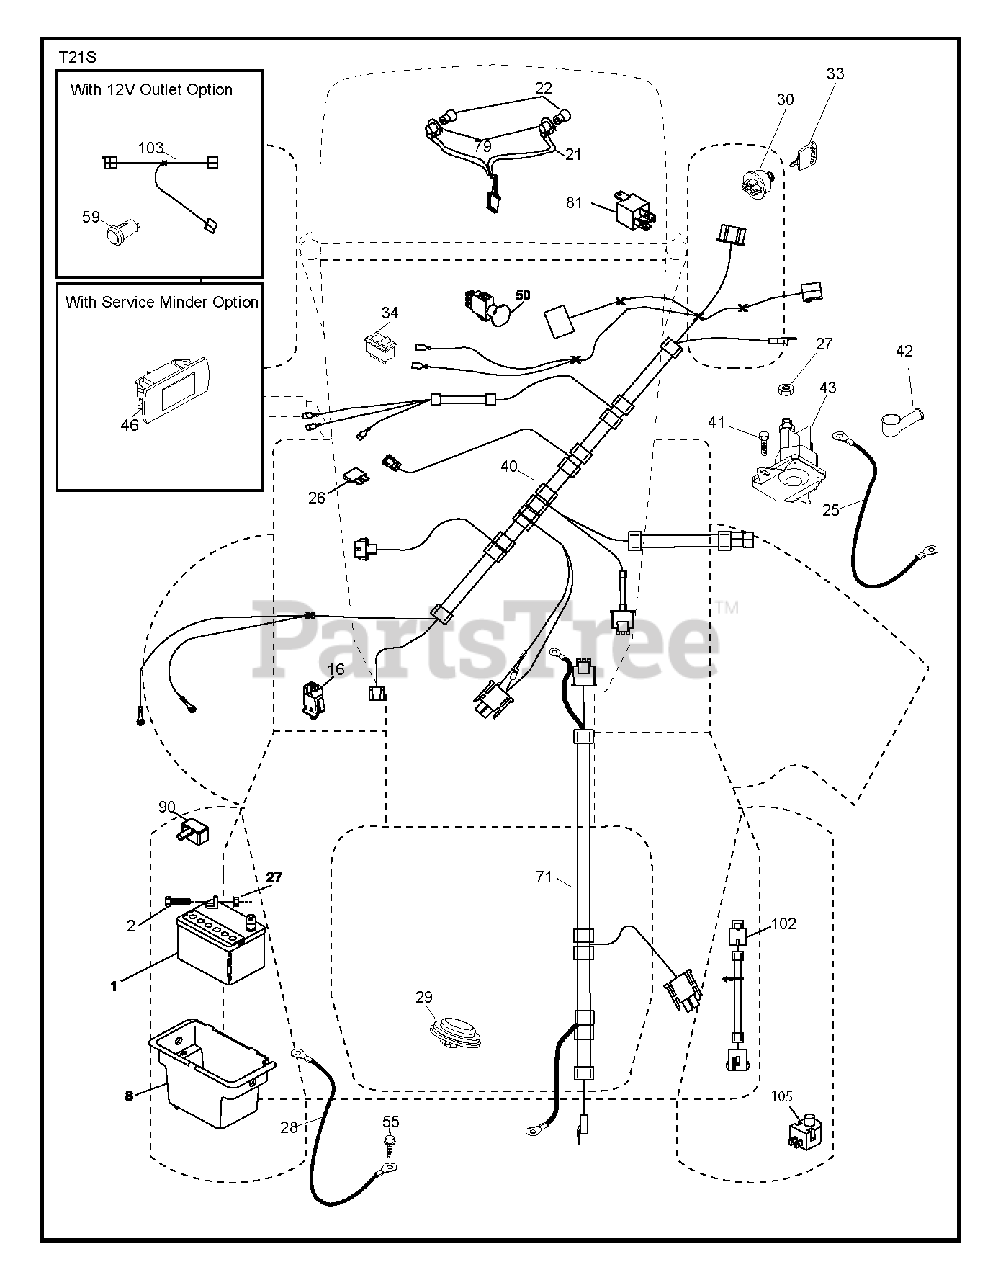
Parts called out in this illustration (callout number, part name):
1	Battery, Dry 30 Amp
2	BOLT.HEX.1/4.X.3/4.DICHROMATE
8	BOX.BATTERY.MNT.REAR.L
16	SWITCH INTERLOOK PUSH-IN
21	HARNESS.LIGHT W/4152J BULBS
25	CABLE.STARTER.8GA.17.5
26	FUSE 20AMP
27	NUT
28	CABLE.GROUND.REAR.BATTERY.8G
29	SWITCH.SEAT.DELTA.OPC.
30	SWITCH.IGN.DELTA.W.LGH.ROS
33	KEY.CHAIN.BLISTER.PACK.GEN.INT
40	HARNESS.IGN.ELEC.RELAY.TEX.46"
41	SCREW
42	TERMINAL COVER
43	SOLENOID.W/BRASS.PLUNGER
46	RP GUAGE.SRVCMNDR.HRMTR.
50	RB PTO.SWITCH.8 TERMINAL.BLACK
55	SCREW 5/16"
71	HARNESS.CHASSIS.TEX.8AWG
79	BULB HOLDER ASM.
81	RELAY HARNESS.SEALED
90	COVER.TERMINAL.BATTERY
102	HARNESS.PIGTAIL.VARIATOR.SD
105	REVERSE SWITCH
